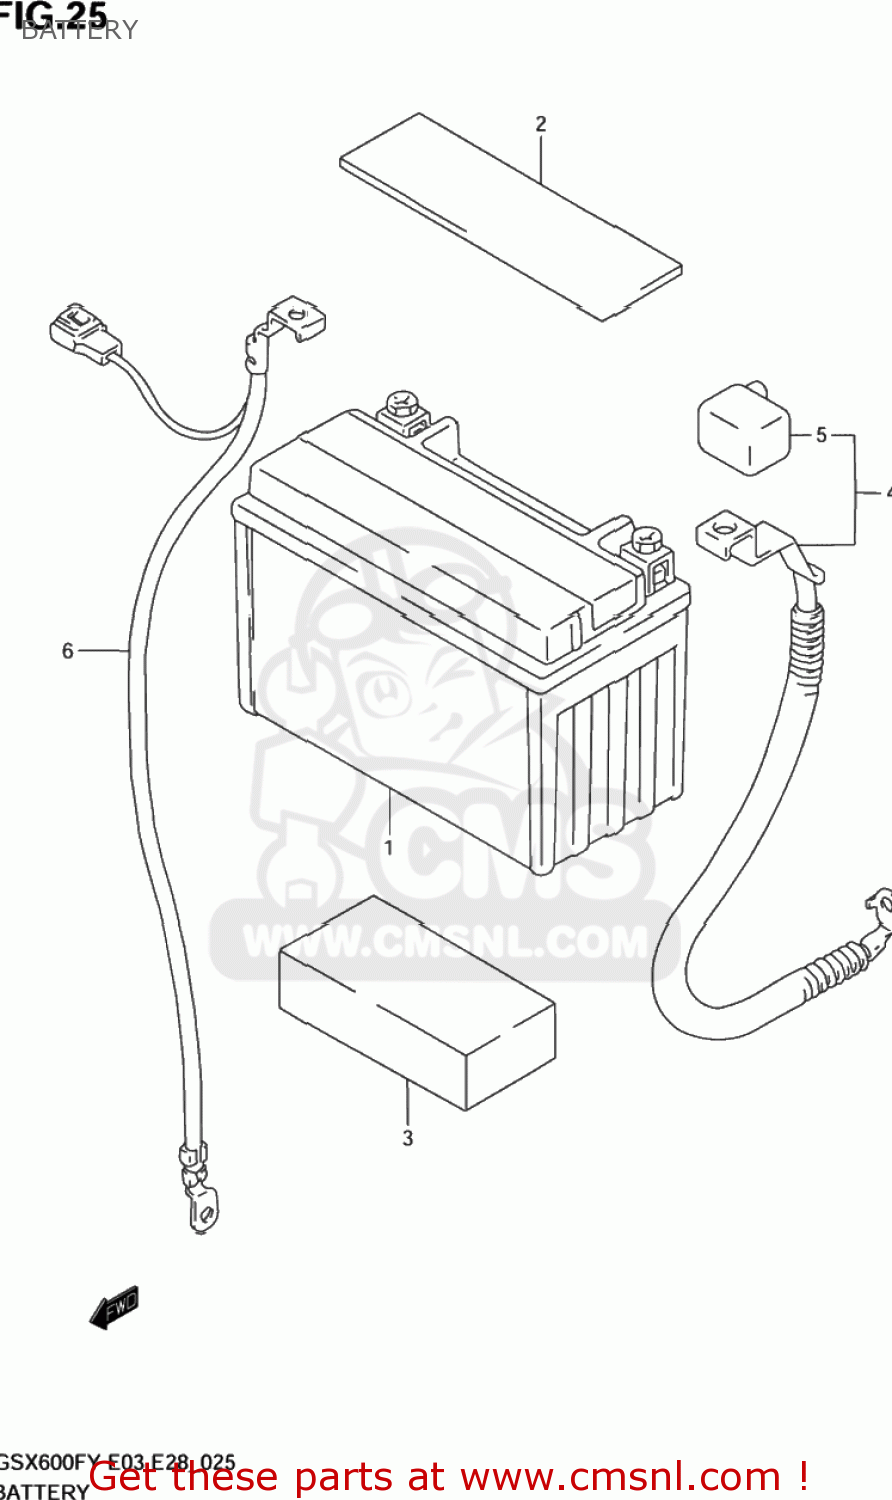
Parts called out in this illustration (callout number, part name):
1	BATTERY ASSY(YTX9-BS,12V8AH)
2	PROTECTOR(170X95X3.0)
3	PROTECTOR(20X50X8)
4	WIRE,BATTERY PLUS LEAD
5	CAP,BATTERY PLUS
6	WIRE,BATTERY MINUS
